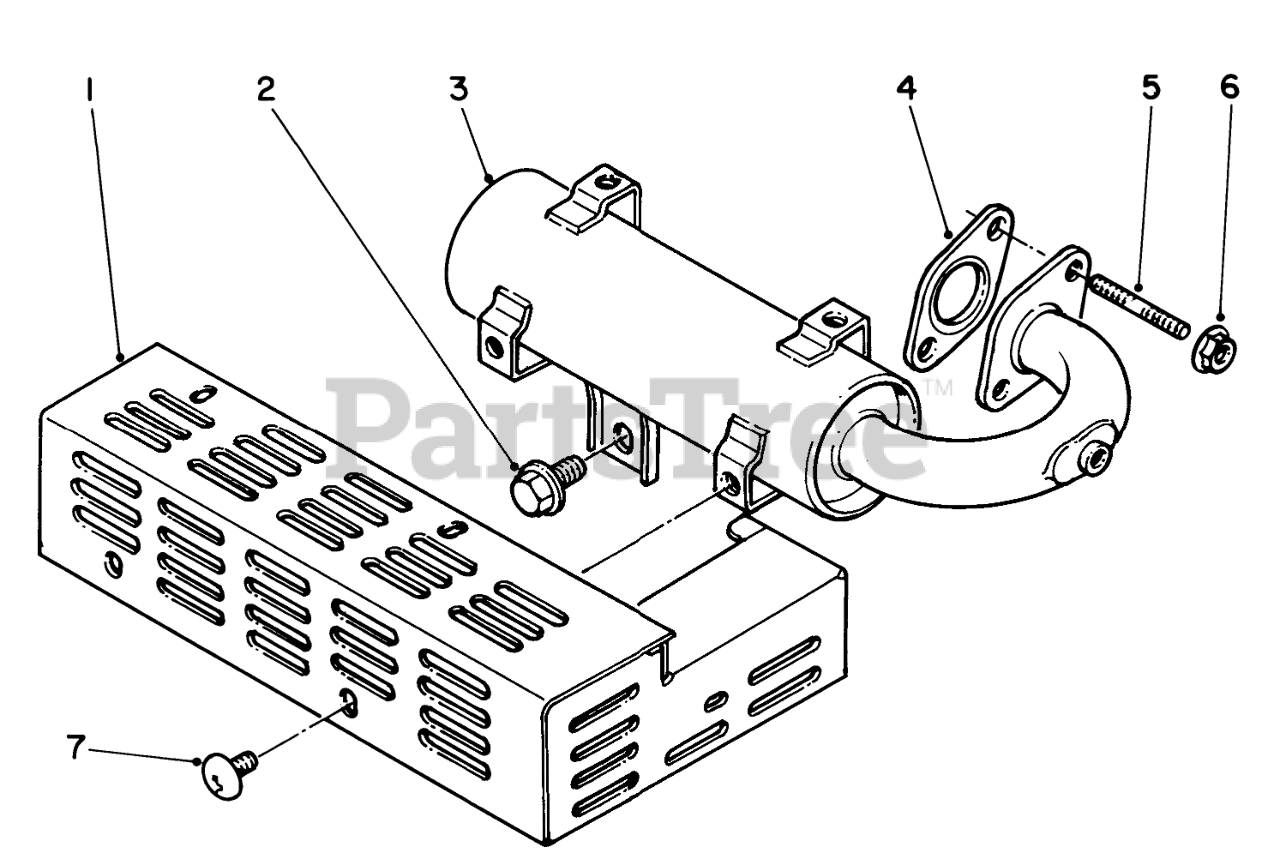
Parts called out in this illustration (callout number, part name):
1	Cover-Muffler
3	Muffler
4	Gasket
5	Bolt-Stud
7	Screw-Round Phillips Hd.
